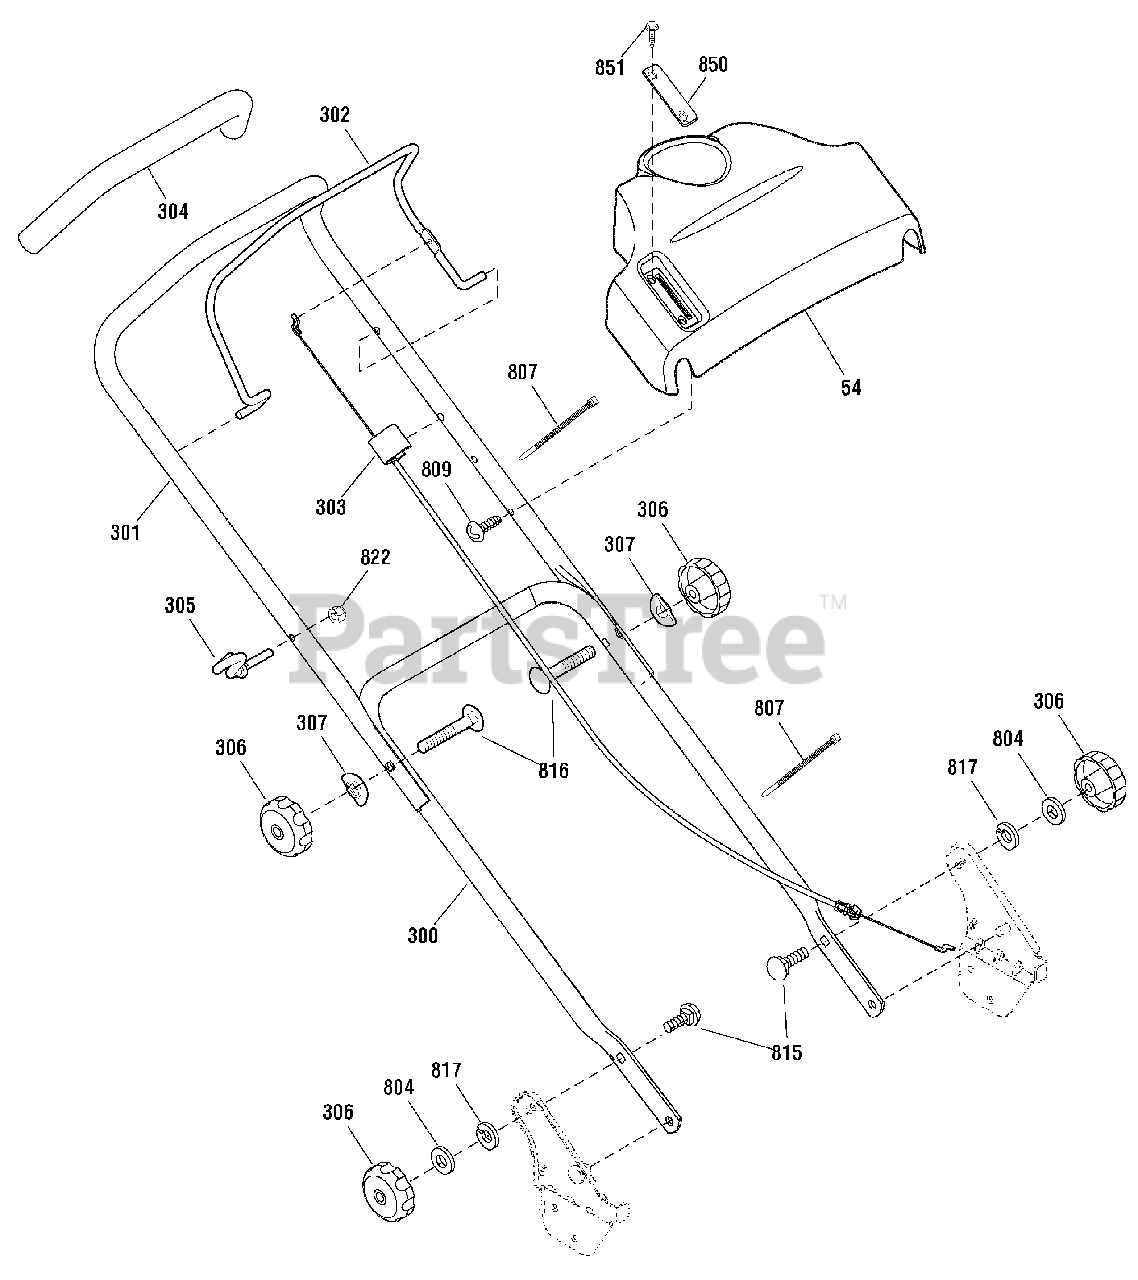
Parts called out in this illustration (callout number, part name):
54	CONTROL PANEL
300	HANDLE, Lower
301	HANDLE, Upper
302	LEVER, Engine Stop
303	CABLE, Engine Stop
304	TUBING, Foam
305	GUIDE, Rope
306	KNOB, Adjuster
307	WASHER, Formed
804	WASHER, 5/8
807	CABLE TIE
809	SCREW, Self Tap, #10-16 x 1/2
815	BOLT, Carriage, 5/16-18 x 1-1/8
816	BOLT, Carriage, 5/16-18 x 2
817	WASHER, Lock
822	NUT, Hex, 1/4-20
850	COVER, Throttle
851	SCREW, 1/4-14 x 3/8
